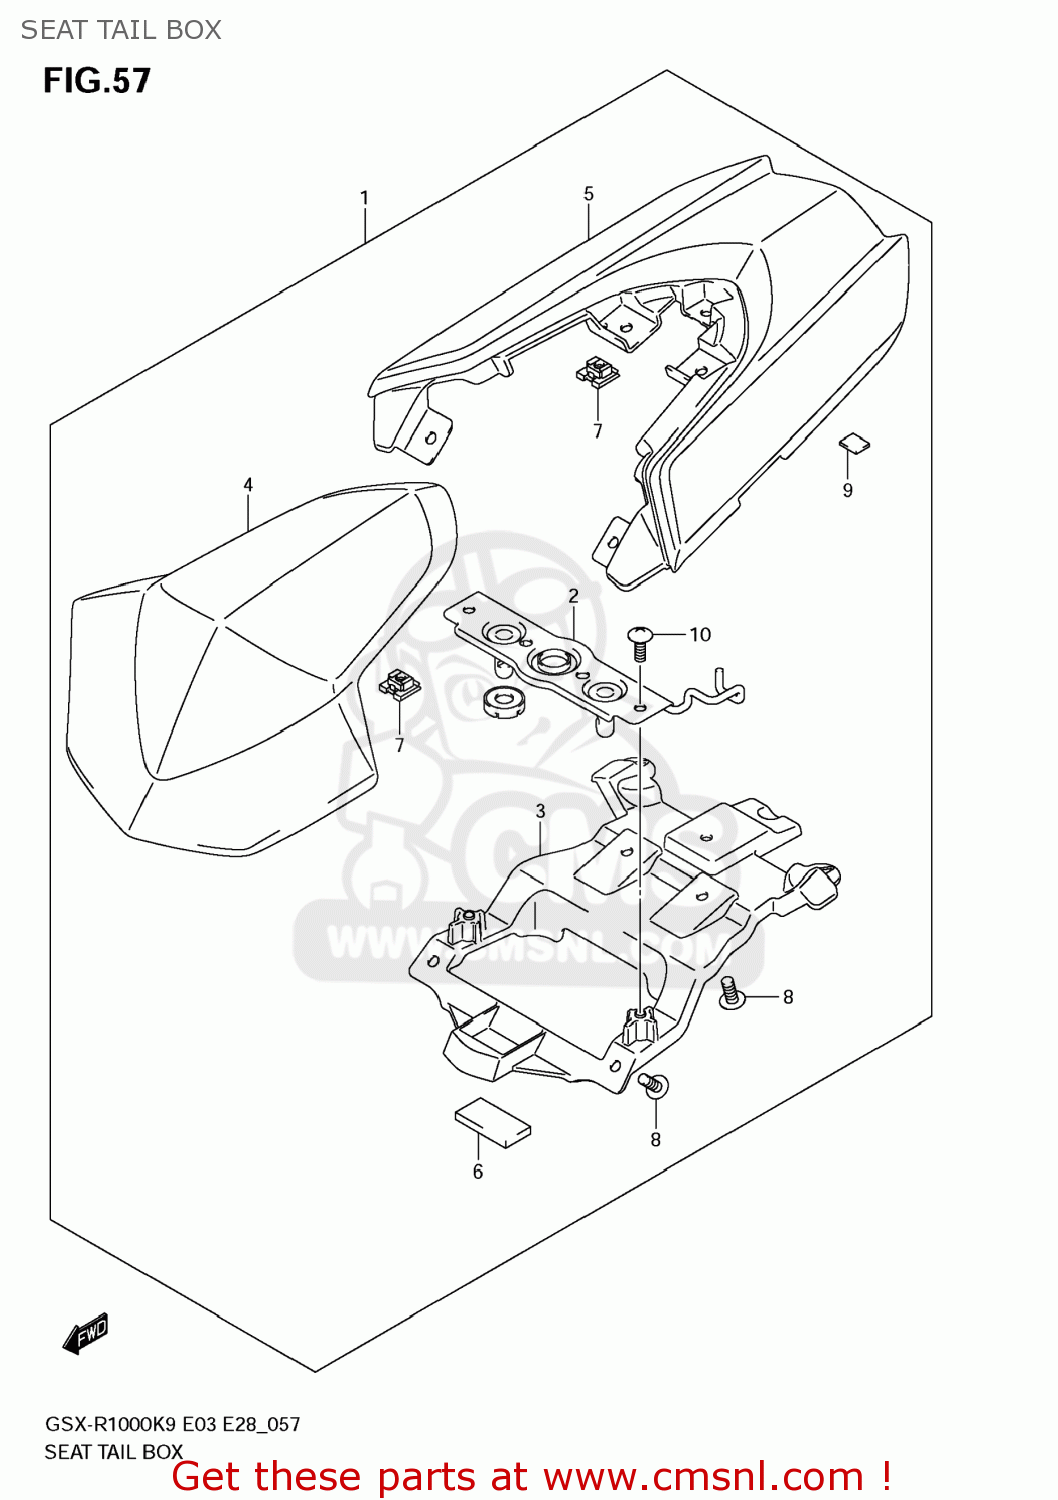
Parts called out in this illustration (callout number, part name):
1	BOX,SEAT TAIL
2	STRIKER,SEAT LOCK
3	FRAME,SEAT TAIL BOX
4	BOX,SEAT TAIL FR
5	BOX,SEAT TAIL RR
6	CUSHION,SEAT TAIL BOX
7	NUT
8	SCREW
9	CUSHION,SEAT TAIL COVER LWR FR
10	SCREW
